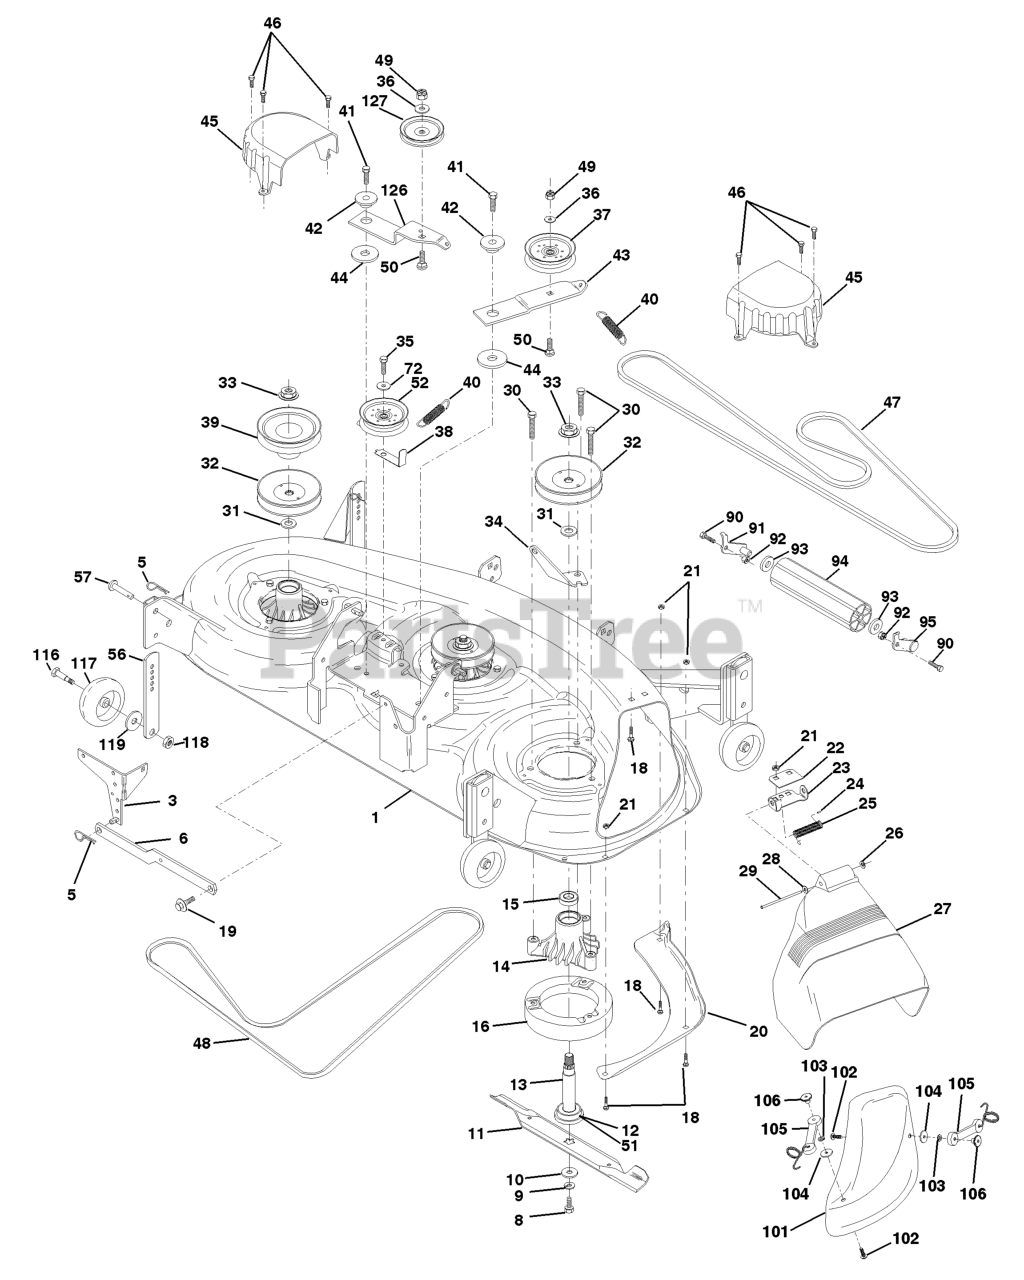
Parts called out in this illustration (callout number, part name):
1	DECK
3	BRACKET SWAY BAR
5	RETAINER-SPRNG RB
6	REAR SUSP ARM
8	BLADE BOLT
9	LOCKWASHER
10	WASHER.BLADE
11	MULCH BLADE
12	BEARING.BALL.#6204.(MANDREL)
13	SHAFT.ASM.W/BEARING
14	HOUSING.MANDREL.44/46" VENT
16	STRIPPER
18	BOLT
19	BOLT SHD 5/16-18
20	BAFFLE, VORTEX MOWER 46"
21	LOCKNUT
22	STIFFENER BRACKET
23	DEFLECTOR BRACKET
24	CAP-SLEEVE LT
25	TORSION SPRING
26	NUT PUSH M
27	DEFLECTOR SHIELD
28	Washer 11/32 x 5/8 x 16 Ga.
29	ROD.HINGE
30	SCREW THDROL ROLLING WASHER HD
31	WASHER
32	PULLEY, MANDREL
33	NUT
34	ANCHOR, SPRING DECK 46"
35	SCREW LT
36	WASHER
37	FLAT IDLER PULLEY
38	KEEPER.BELT.IDLER
39	PULLEY.DRIVEN.DECK.46"
40	SPRING.SEC.44"VEN
41	SCREW
42	SPACER RETAINER
43	ARM IDLER DECK 46"
44	HARDENED WASHER
45	COVER MANDREL 46
46	SCREW.1/4-20X5/8
47	BELT V SECONDARY
48	V-BELT.PRMRY 46/50 VENT.BLK BK
50	BOLT.3/8-16X1.50
51	WASHER FELT
52	PULLEY IDLER FLAT 46 PRI DRIVE
56	BAR.ADJUST.WHEEL.ANTI.SCALP.BL
57	RIVET.PIN.HEAD.YELLOW.
72	WASHER
90	BOLT
91	BRACKET LH (A)
92	NUT
93	Washer 17/32 x 7/8 x 16 Ga.
94	NOSE ROLLER
95	BRACKET RH (B)
101	COVER.MULCH.46"3-BLADE.(2 2)
102	SCREW
103	LOCKWASHER #10
105	Latch Asm. Mulch/Bagger
106	WELDNUT
116	BOLT, SHOULDER
117	WHEEL GAGE DONUT
118	LOCKNUT
119	WASHER.5/16.FLAT.STE.STD.
126	ARM IDLER PRIM 46
127	PULLEY.IDLER.4.25
